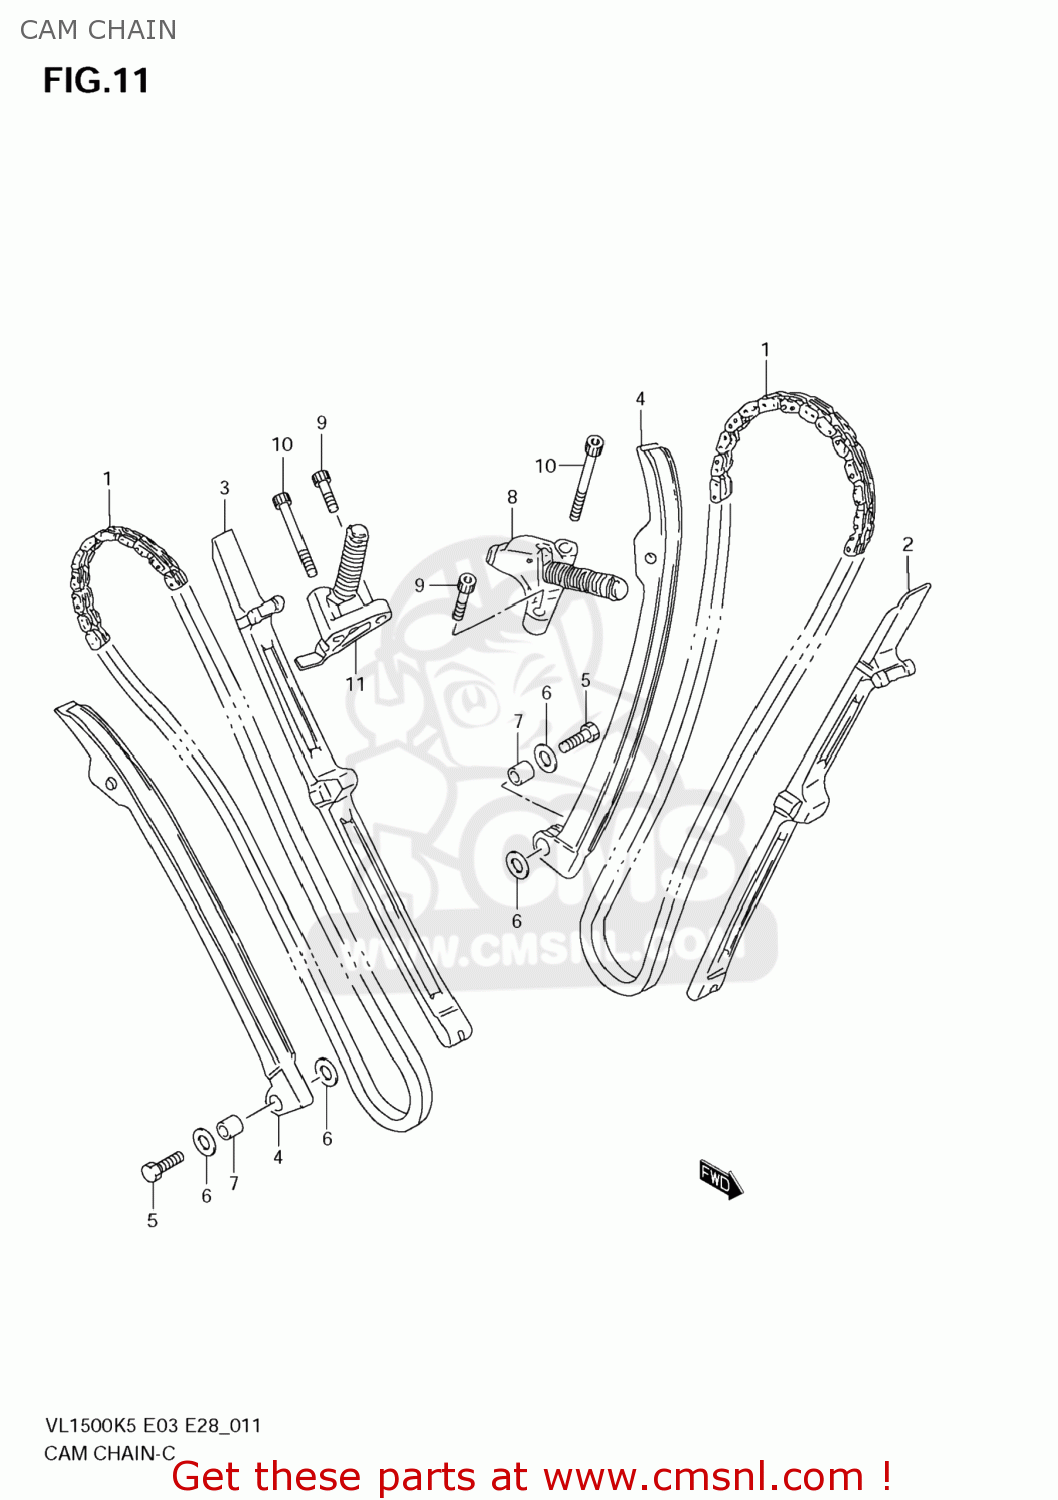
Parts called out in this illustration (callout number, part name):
1	CHAIN,CAMSHAFT DRIVE
2	GUIDE,CAM CHAIN
3	GUIDE,CAM CHAIN RR
4	TENSIONER,CAM CHAIN
5	BOLT(6X26)
6	WASHER
7	SPACER(6X11X9)
8	ADJUSTER ASSY,FR TENSIONER
9	BOLT
10	BOLT
11	ADJUSTER ASSY,RR TENSIONER
